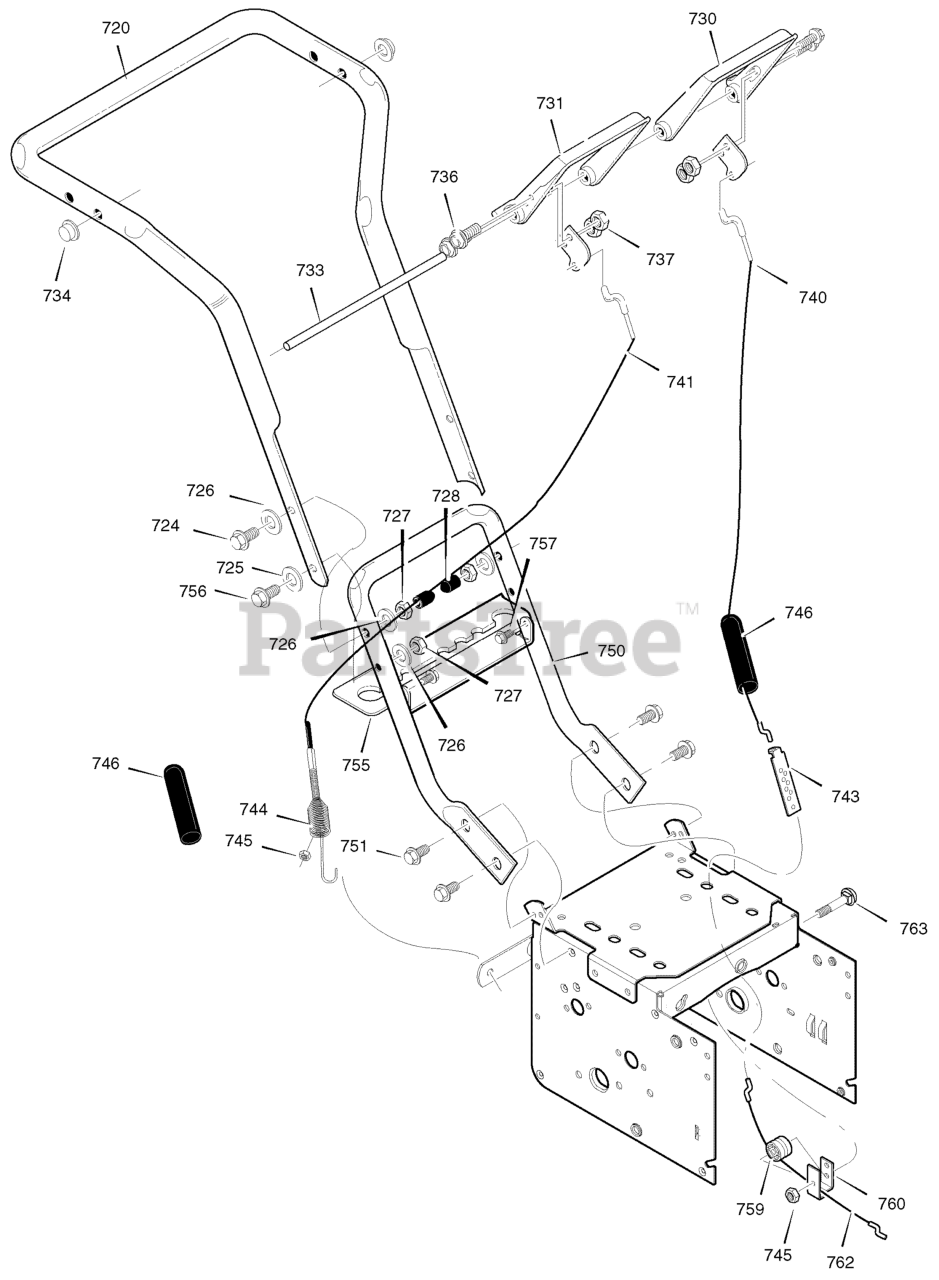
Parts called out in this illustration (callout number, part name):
724	SCREW 5/16-18 x 2.75
725	WASHER, FLAT
726	WASHER
727	NUT 5/16-18
728	PLASTIC-STOP
730	CLUTCH, LEFT HANDLE CONTROL
731	CLUTCH, RIGHT HANDLE CONTROL
733	ROD, PIVOT HANDLE
734	PUSH ON CAP
735	PLATE, CABLE PIVOT
736	SCREW 1/4-20 x 0.88
737	NUT 1/4-20
740	CABLE, CLUTCH
741	CABLE, AUGER CLUTCH
743	BRKT, CABLE ADJUST
744	SPRING, AUGER CLUTCH
745	LOCKNUT
746	BOOT, CLUTCH SPRING
750	HANDLE, LOWER
751	SCREW 51/16-18 x 0.75
752	WASHER
755	BRACKET, GEAR SELECTOR
756	SCREW, .31-18 x 2.00
757	SCREW, 1/4-20 X 0.62
759	SPOOL-CABLE, AUGRT CLUTCH
760	BRACKET, CABLE SPOOL YZ
762	CABLE, LOWER DRIVE 12"
763	BOLT, HEX 1/4-20 X 1.50 YZ
